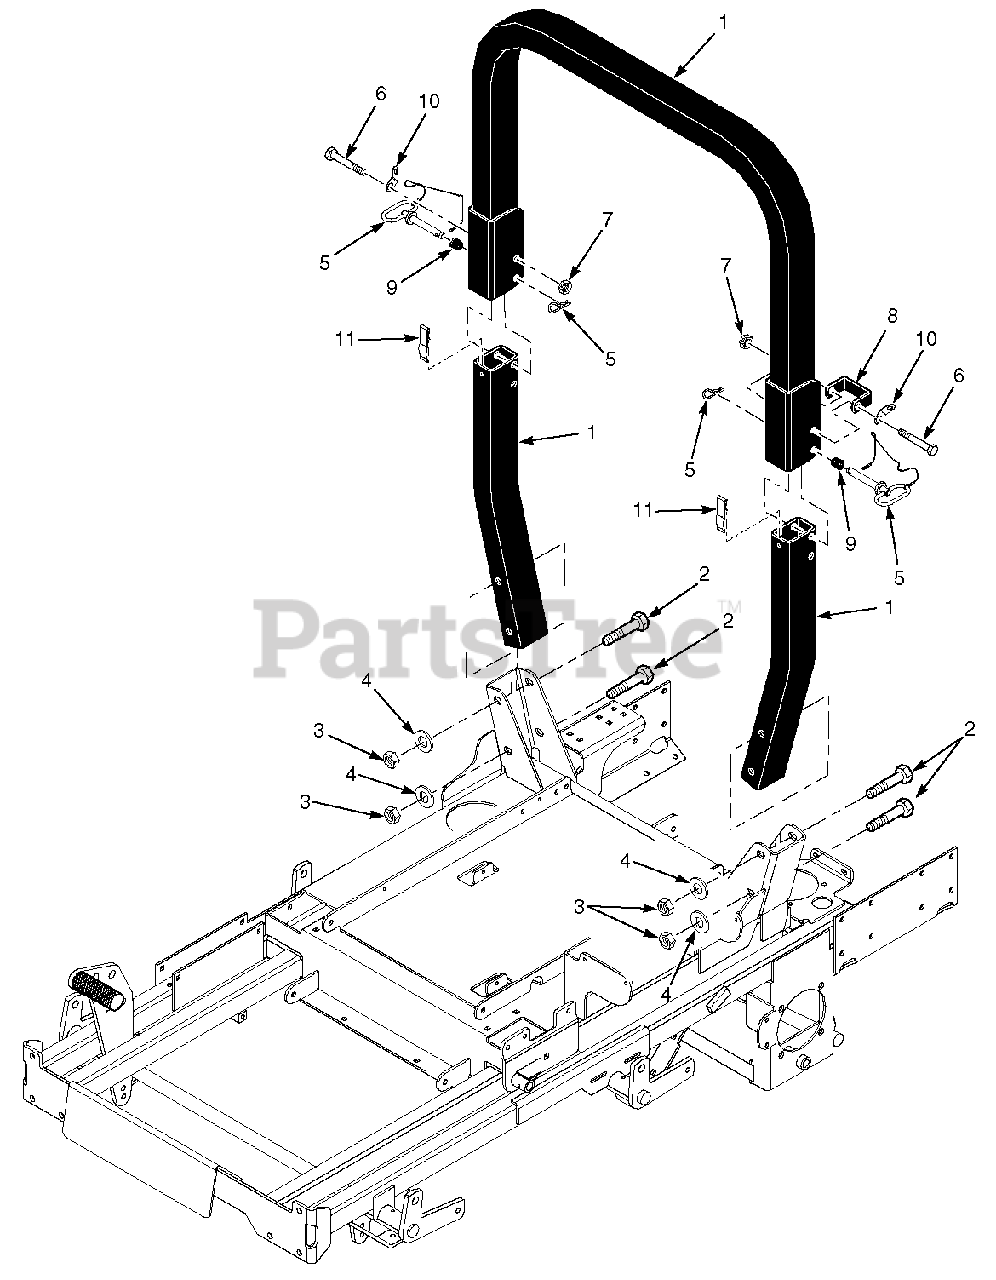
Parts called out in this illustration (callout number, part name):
1	STT, ROPS
2	Bolt, Hex Head 1/2-13 x 4-1/2" (upper)
2	Bolt, Hex Head 1/2-13 x 4" (lower)
3	Nut, Center Lock 1/2-13
4	Flatwasher, 1/2-.562 x 1.375 x .109
5	Pin Assembly
6	Bolt, Hex Head 1/2-13 x 3-3/4"
7	Nut, Center Lock 1/2-13
8	Stop Bracket, ROPS
9	Spring, ROPS
10	Clip, ROPS
11	Spring Clip, ROPS
